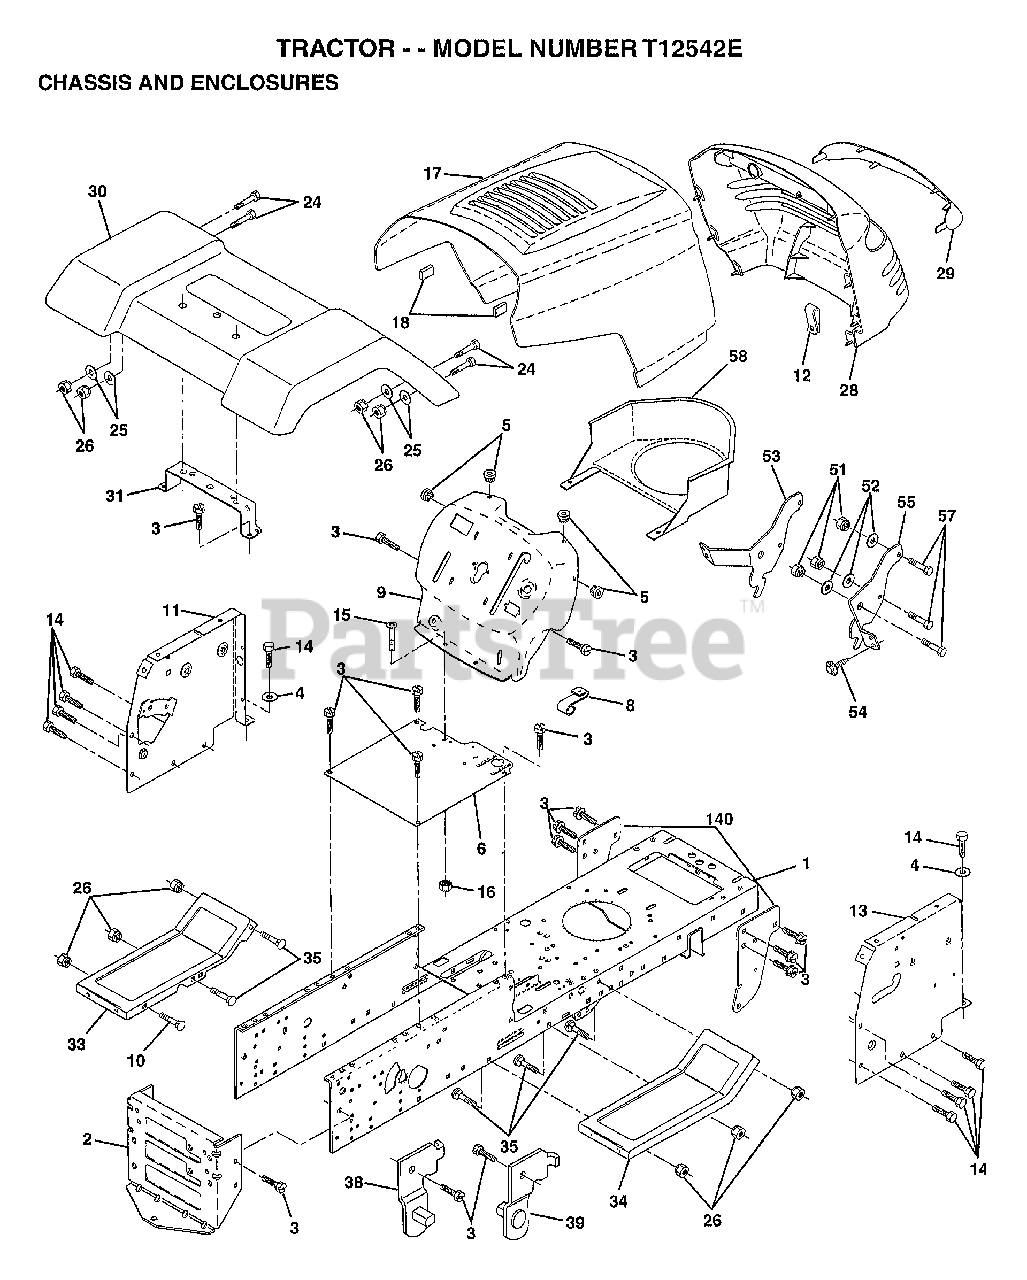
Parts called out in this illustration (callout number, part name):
1	CHASSIS ASM
3	SCREW
4	WASHER
5	BUMPER-HOOD/DASH
6	SADDLE
8	CLIP.RETAINER
9	DASH.SILKSCREENED
11	"PANEL-DASH,LH"
12	CLIP.TINNERMAN
14	SCREW LT
15	SCREW
24	BOLT
25	WASHER
26	NUT
28	GRILLE-MS428
29	LENS GRILLE
31	BRKT FENDER
33	FOOTREST.LH.PERF.
34	FOOTREST.RH.PERF.
35	BOLT
38	BRACKET ASM LH
39	BRACKET ASM RH
51	NUT
52	WASHER
53	BRACKET.GRILLE.LH
55	BRACKET.GRILLE.RH
58	AIR DUCT
140	BRKT SUSPENSION
